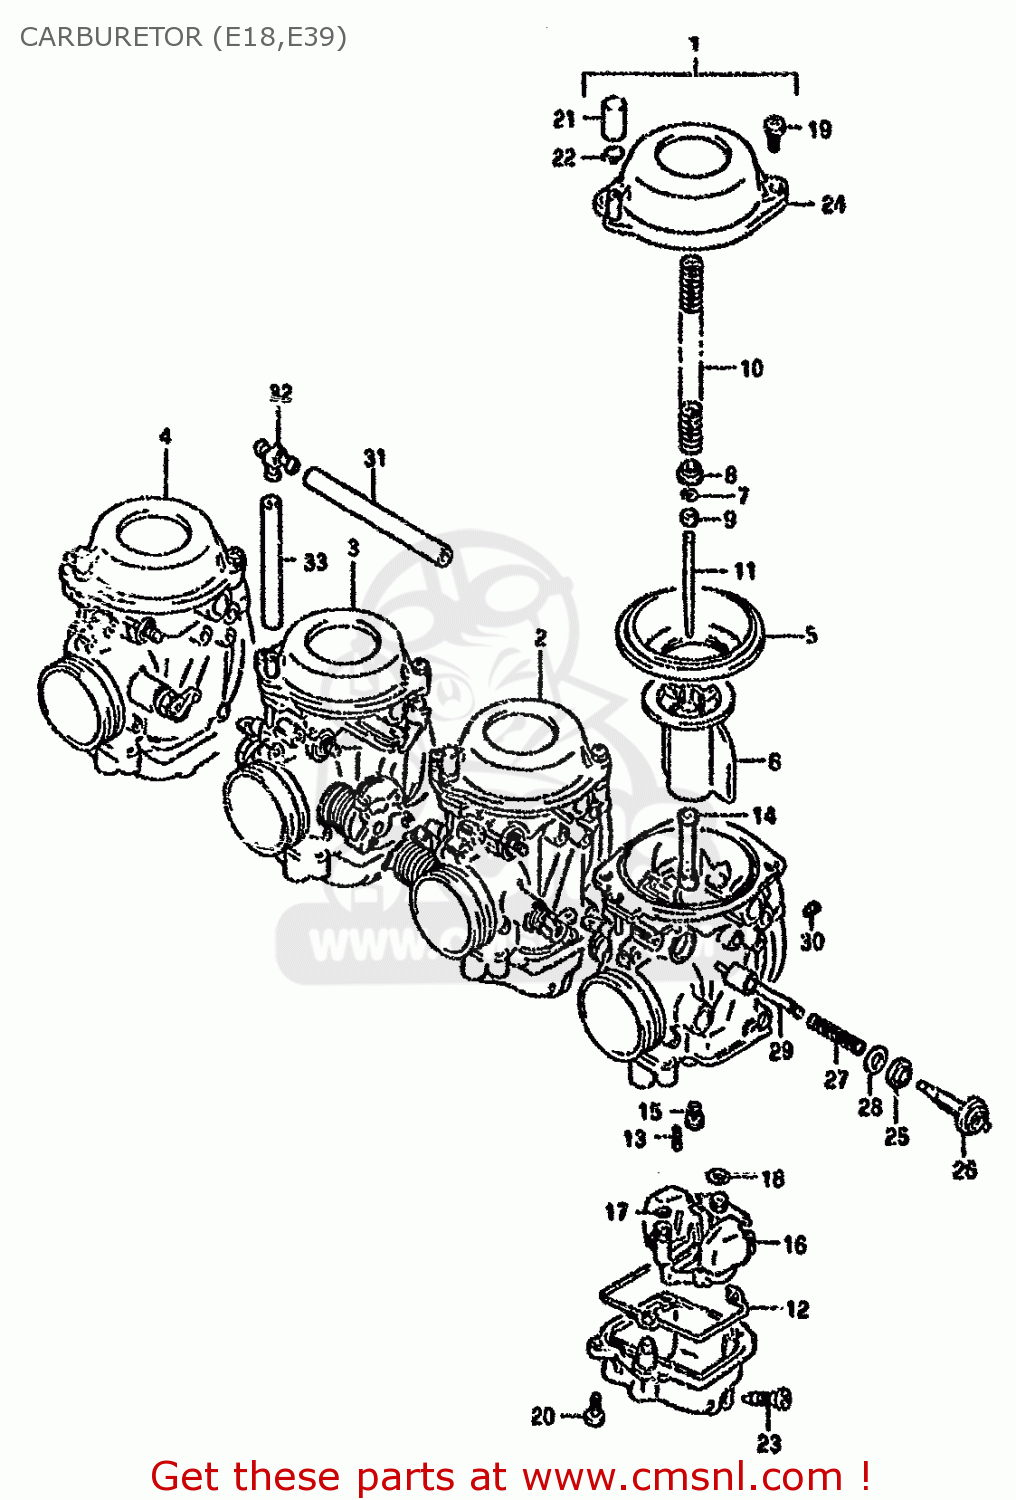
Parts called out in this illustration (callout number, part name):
1	CARBURETOR ASSY,LH
2	CARBURETOR ASSY,ML
3	CARBURETOR ASSY,MR
4	CARBURETOR ASSY,RH
5	DIAPHRAGM
6	VALVE,PISTON
7	CLIP
8	RING
9	RING
10	SPRING
11	NEEDLE,JET
12	GASKET,FLOAT CHAMBER (NAS)
13	JET,PILOT(37.5)
14	JET,NEEDLE(P-3)
15	JET,MAIN(110)
16	FLOAT/NEEDLE VALVE ASSEMBLY
17	O RING
18	O-RING,NEEDLE VALVE
19	SCREW
20	SCREW
21	CAP
22	CLIP
23	SCREW,DRAIN
24	COVER,DIAPHRAGM
25	SCREW
26	CAP
27	CLIP
28	WASHER
29	COVER,DIAPHRAGM
30	CAP,STARTER
31	HOLDER,GUIDE
32	NIPPLE
33	WASHER
34	PLUNGER ASSY
35	JET,AIR(0.5)
36	JET,AIR(1.3)
37	SCREW,PILOT
38	SPRING
39	WASHER
40	O RING,PILOT AIR SCREW
